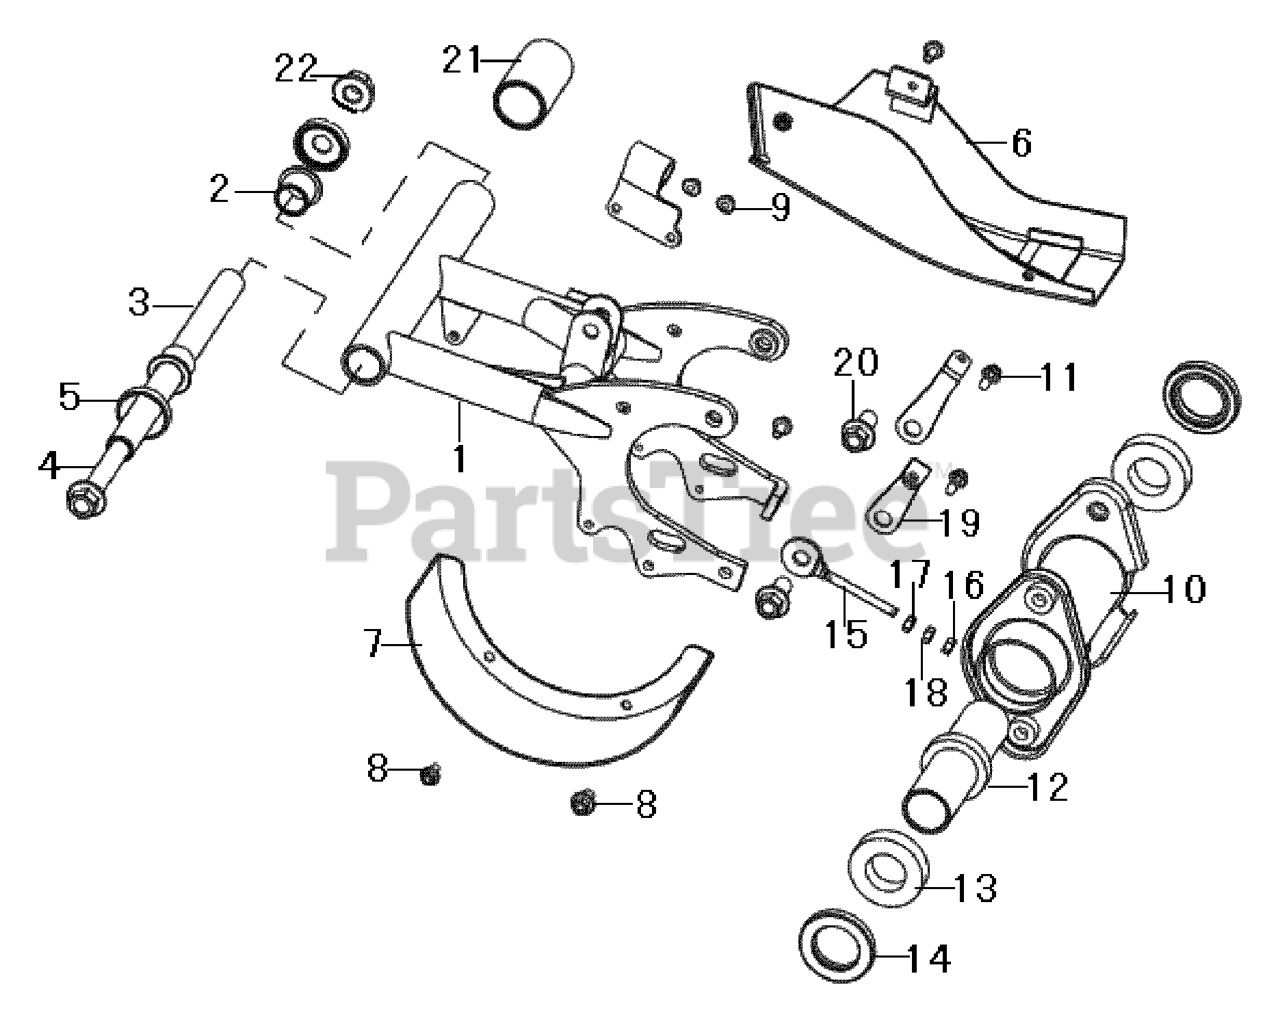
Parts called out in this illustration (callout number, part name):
1	SWING ARM, REAR
2	BUSHING
4	BOLT, SWING ARM
10	AXLE HOUSING
12	AXLE COLLAR, REAR
13	BEARING
15	ADJUSTER, CHAIN
19	BRACKET
